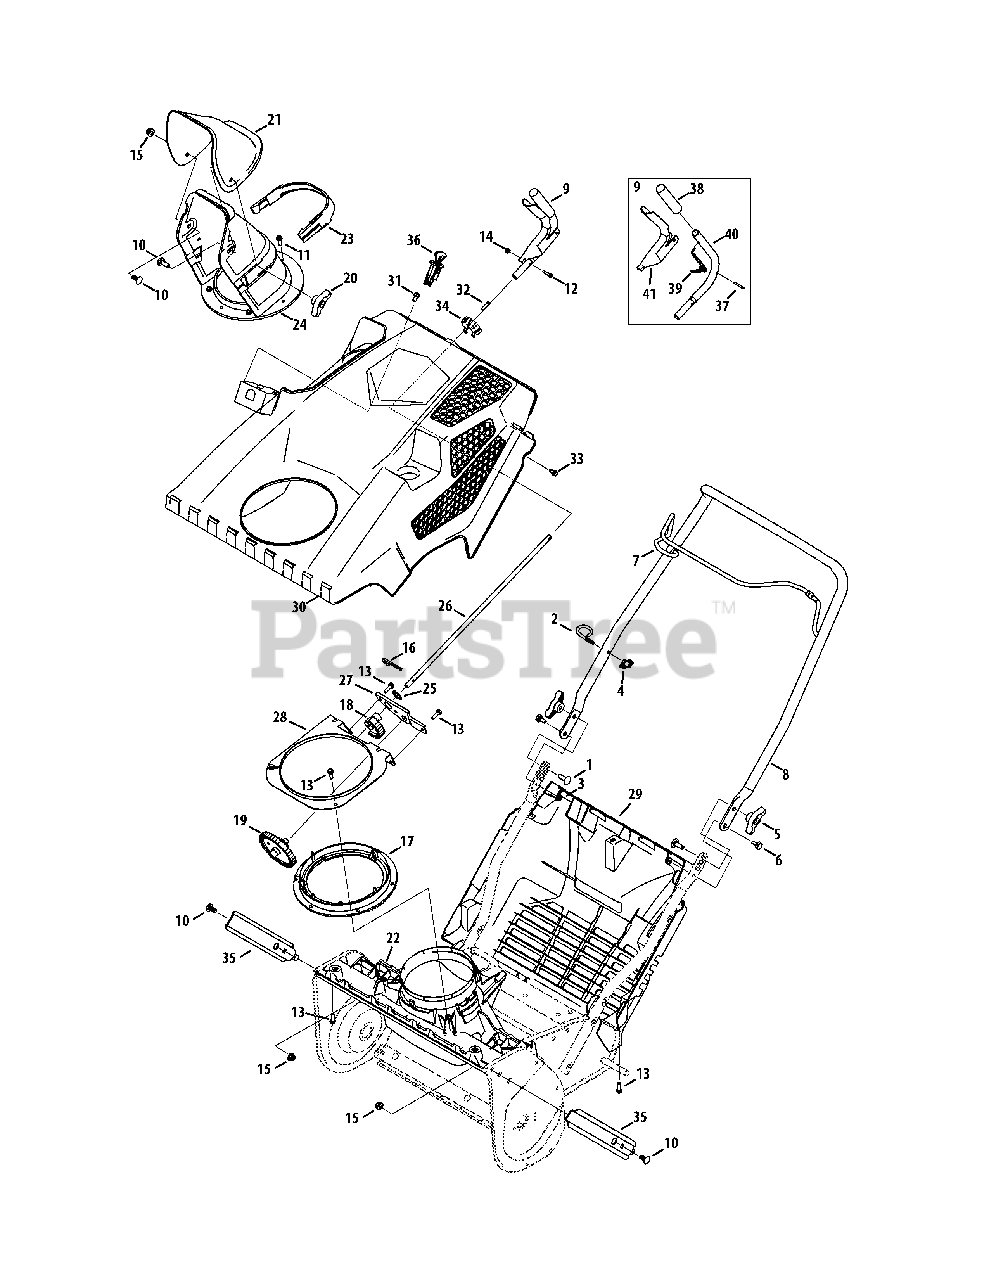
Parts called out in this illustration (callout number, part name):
1	Carriage Bolt, 5/16-18 x 1.00
2	Eye Bolt, 1/4-20
3	Flange Lock Nut, 1/4-20
4	Knob Handle
6	Shoulder Screw, .375 x .148 x 1/4-20
8	Upper Handle
9	Chute Control Assembly
10	Carriage Bolt, 5/16-18 x .75
11	Hex Washer Screw, 1/4 x .750
12	Screw, #8-32 x .875
13	Screw, Hi-Lo:1/4-15, 0.75
14	Hex Lock Nut, #8-32
15	Flange Lock Nut, 5/16-18
16	Cotter Pin
17	Bevel Gear, 95T
18	Spur Gear, 35T
19	Bevel Gear, 40T/11T
20	Wing Knob, 5/16-18
21	Upper Chute
22	Chute Adapter
23	Chute Plug
24	Lower Chute
25	Flat Washer, .75 x 1.00 x .06
27	Gear Mounting Plate
28	Gear Retainer Bracket
29	Bottom Cover
30	Top Cover
31	Hex Washer Screw, 1/4-15 x .50
32	Hex Washer Screw, #8-16 x .50
33	Hex Washer Screw, 1/4-20 x .625
34	Index Bracket
36	Ignition Switch Assembly
39	Torsion Spring
40	Chute Rotation Tube
41	Chute Rotation Bracket
